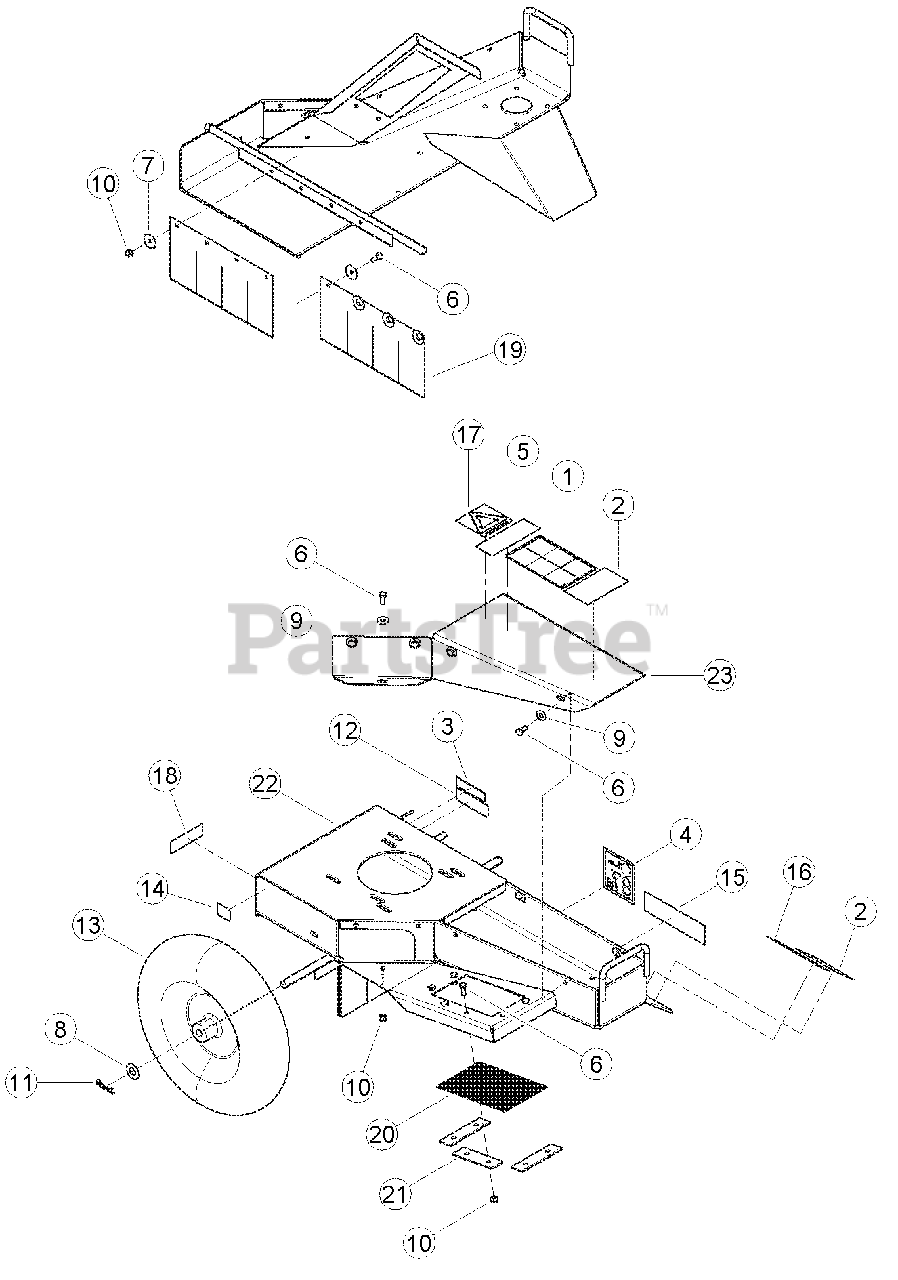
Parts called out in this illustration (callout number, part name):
1	DECAL, OPERATING INSTRUCTIONS ISO
2	DECAL, GRINDER DANGER
3	DECAL, STUMPGRINDER INFO
4	DECAL, 87 DB
5	DECAL, MULTILINGUAL MANUAL
6	BOLT, 5/16 X 3/4 HEX HD GR5 ZP
7	WASHER, 5/16 FENDER ZP
8	WASHER, 5/8 SAE FLAT ZP
9	WASHER, 5/16 FLAT ZP
10	NUT, 5/16 NE NYLOCK ZP
11	HAIRPIN CLIP ZP #203
12	DECAL, SERIAL NUMBER
13	TIRE, 480/400 X 8 WHEELBARROW
14	DECAL, CE APPROVAL
15	DECAL, ECHO BEARCAT 6.82 X 1.90
16	DECAL, MODEL SG340
17	DECAL, SMALL RECLAIM IT
18	DECAL, ATLANTIC BRIDGE LTD INFO
19	MUD FLAP, STUMP GRINDER
20	DEBRIS SCREEN, STUMP GRINDER
21	SCREEN CLAMP, STUMP GRINDER
22	WELDMENT, STUMP GRINDER FRAME
23	COVER, TOP STUMP GRINDER
